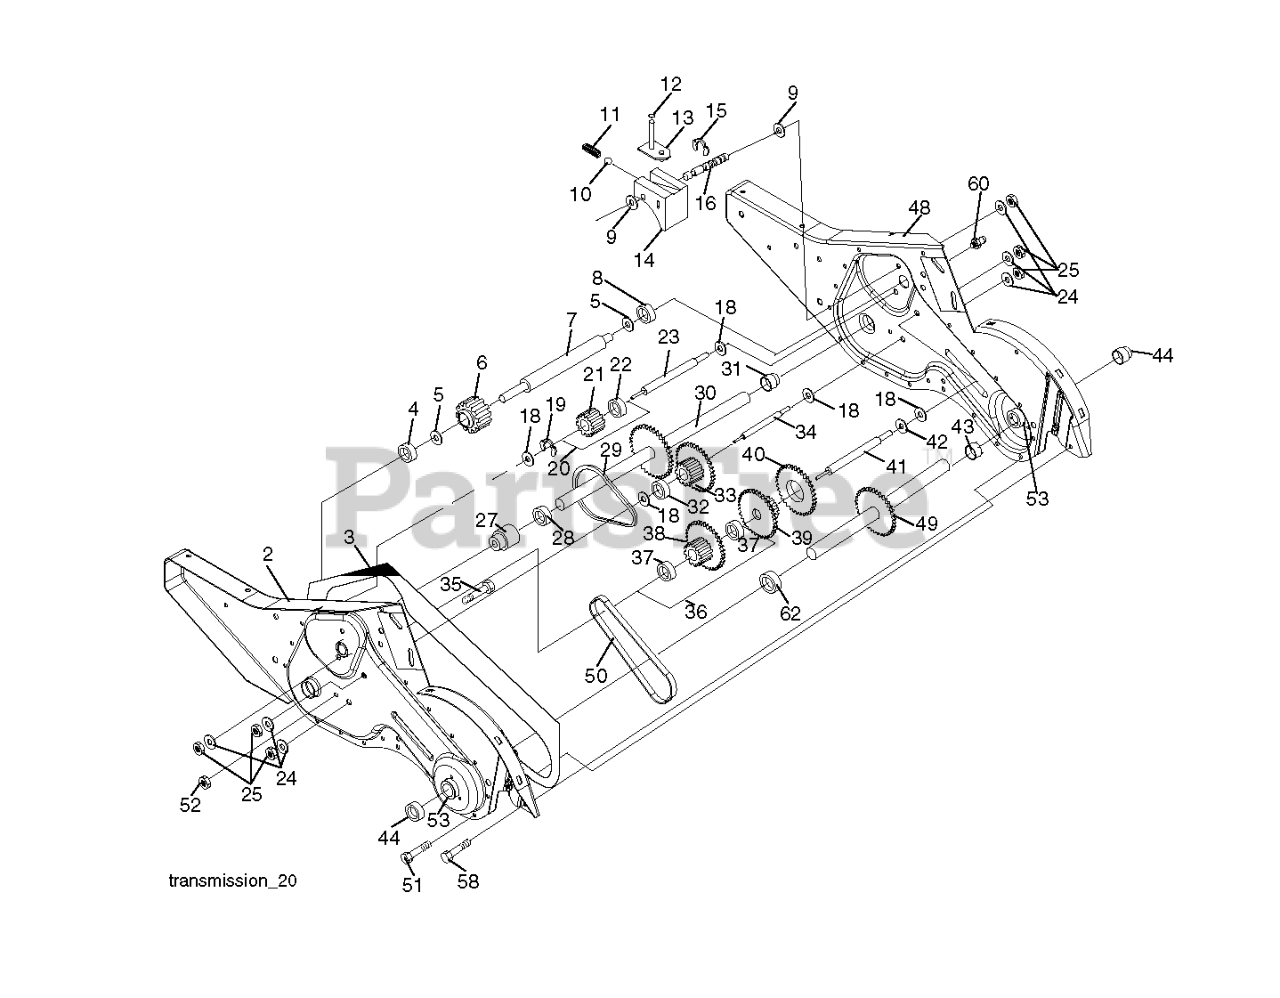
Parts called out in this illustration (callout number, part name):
1	TRANSMISSION ASM.
2	GEARCASE.ASM.CRT.LH.W/BEARING
3	GASKET.GEARCASE.CRT/DRT.TILLER
4	NEEDLE BRNG LT
5	THRUST WASHER
6	GEAR.PINION.INPUT
7	SHAFT.INPUT."D".TILLER
8	BEARING TI
9	WASHER, SEAL (2 2)
10	STEEL BALL KIT
11	SPRING-SHIFT CRT
13	BRACKET ASM.SHIFT.CRT
14	SHIFT FORK TI
16	SHAFT.SHIFTER.TILLER
20	GEAR ASSY CRT
21	GEAR-REV IDLR CRT
22	NEEDLE BEARING TI
24	LOCKWASHER
25	NUT.ASF.HEX.7/16
27	BEARING.GROUND.DRIVE
30	GROUND SHAFT ASS'Y
31	BEARING, SHAFT RH CRT
33	SPRCKT 8 GEAR CRT
34	SHAFT.SECONDARY.REDUCTION.CRT
35	SCRW WHIZ LOK CRT
36	SPROCKET.ASM.W/BEARING.TILLER
37	BEARING
38	SPROCKET, TINE
41	SHAFT.REDUCTION.TILLER
42	BRNG RACE T
44	SEAL ASM, OIL
48	GEARCASE.ASM.CRT.RH.W/BEARING
49	SHAFT.ASM.TINE
50	CHAIN.TILLER
51	SCREW
52	NUT
53	KIT.BEARING.TILLER.
58	BOLT SHOULDER 1/4-20 UNC X.875
60	FITTING.GREASE.TAPERED
62	SPACER.1.015X1.50X.650
